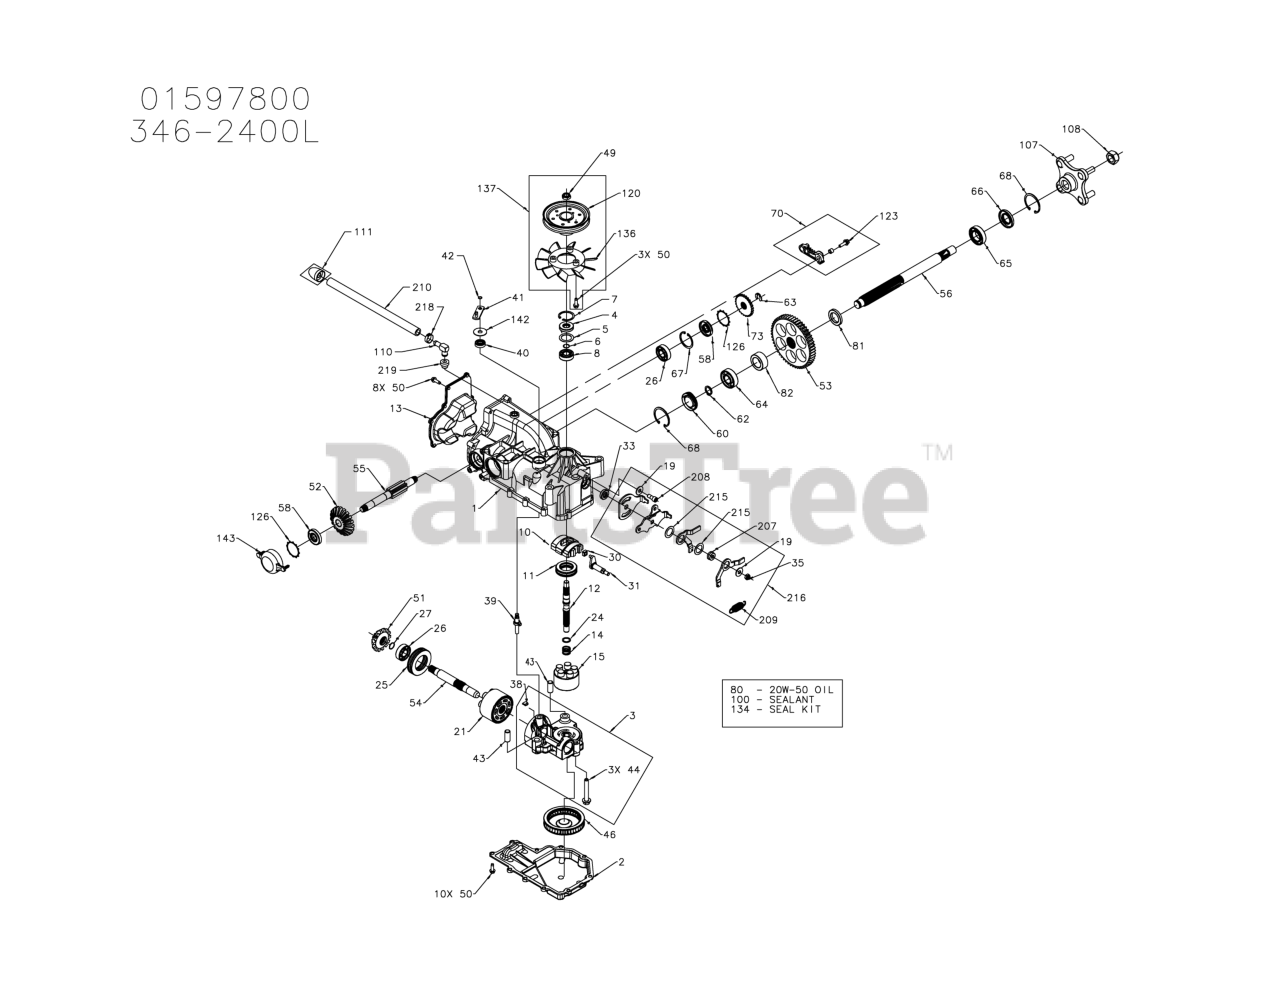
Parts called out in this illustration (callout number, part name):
1	KIT, SHAFT-MAIN HOUSING
2	HSG, IZT LOWER
3	KIT, C-SECTION
4	SEAL, LIP 15X35X7
5	WASHER .98X1.37X.04
6	RING, WIRE RETAINING
7	RING. RETAINING
8	BEARING, SHAFT BALL
10	SWASHPLATE. VARIABLE
11	BEARING. THRUST 30 X 52 X 13
12	SHAFT, INPUT
13	COVER, END IZT
14	SPRING. BLOCK
15	KIT, 10 CC BLOCK
21	ASSEMBLY BLOCK
24	WASHER. THRUST .59 X .79 X .04
25	BRG, THRUST BALL 42X68X16
26	BRG, BALL 17X40X12
27	RING, RET WIRE .561 ID
30	GUIDE. SLOT
31	ARM. TRUNNION TAPERED SQUARE
33	SEAL, LIP 12X25X7
39	ACTUATOR, BYPASS
40	SEAL, LIP
41	ARM. BYPASS
42	RING, RETAINING
50	HFHCS 1/4-20X.75
51	GEAR, BEVEL 14T
52	GEAR, BEVEL 19T
53	GEAR, SPUR 53T
54	SHAFT, MOTOR
55	SHAFT, BRAKE
56	AXLE, 1.0X12.3
58	SEAL, LIP 17X40X7
60	PLUG, SEAL 1.86
62	RING, RET .75 EXT
63	RING, RET .440 EXT
64	BRG, BALL 20X47X14
65	BRG, BALL 25X47X12
66	SEAL, LIP 25X47X7
67	RING, RET 1.56 INT
68	RING, RET 1.87 INT
70	BRAKE ARM, LH IZT
73	BRAKE, PARK SPLINE
80	FLUID, HYDRO 20W50 QT
80	FLUID, HYDRO 15W50 QT
100	SEALANT TUBE 10.1OZ.
107	ASSEMBLY, HUB
126	RING, RET 1.43"
134	KIT, SEAL
137	KIT, FAN/PULLEY
142	WASHER, .392 X 1.250 X .0
143	CAP, BRAKE
216	BREATHER ASSEMBLY
219	BUSHING-VENT (RUBBER)
